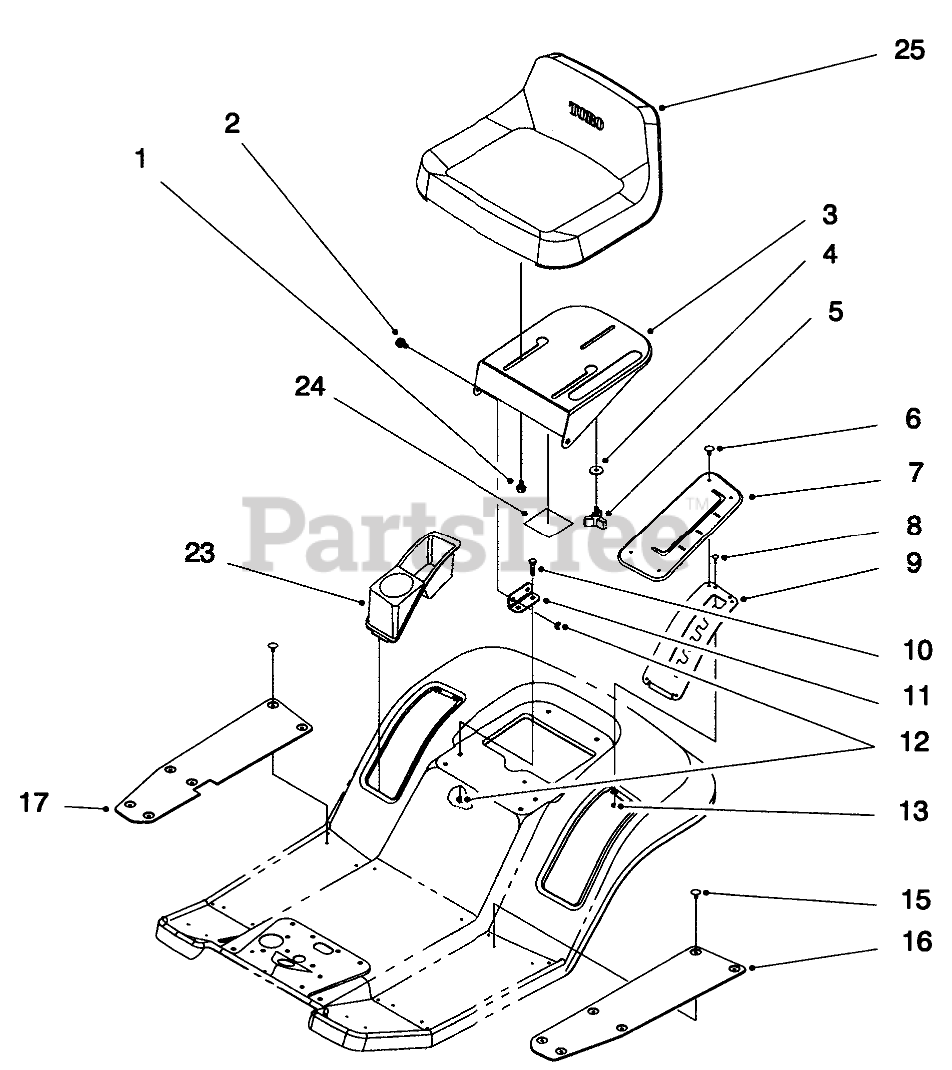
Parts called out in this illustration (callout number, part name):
1	BOLT-SHOULDER
2	BOLT-SHOULDER
3	Support-Seat
4	WASHER-PIVOT
6	FASTENER-PANEL
7	COVER-HOC
8	RIVET-BLIND
9	Gate-H.O.C.
10	SCREW-HH
11	Bracket-Seat Hinge
12	NUT-LOCK, NI
13	WASHER-PLAIN
15	FASTENER-PANEL
16	MAT-FOOT, LH
17	MAT-FOOT, RH
23	TRAY-FENDER
24	DECAL-EUROPE
25	SEAT-V-511
